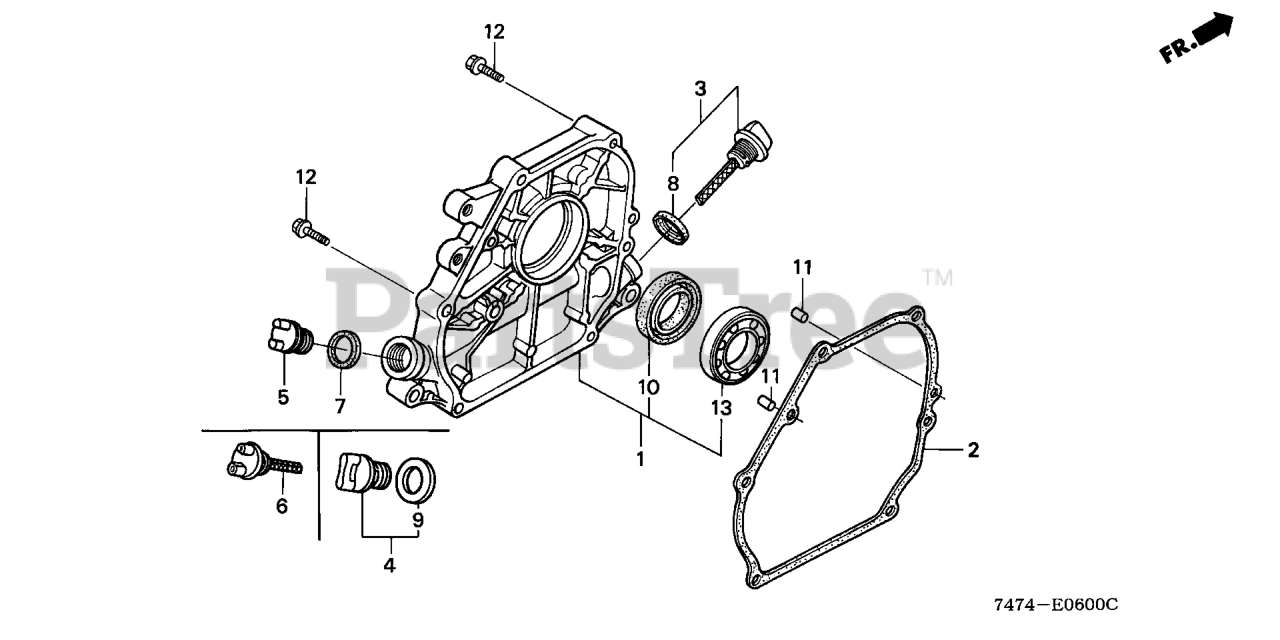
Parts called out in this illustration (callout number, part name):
1	COVER ASSY., CRANKCASE
2	GASKET, CASE COVER (NON-ASBESTOS)
3	CAP ASSY., OIL FILLER
4	CAP ASSY., OIL FILLER
8	GASKET, OIL FILLER CAP
9	GASKET, OIL FILLER CAP
10	OIL SEAL (25X41X6)
11	PIN A, DOWEL (8X14)
12	BOLT, FLANGE (8X32)
13	BEARING, RADIAL BALL (6205)
